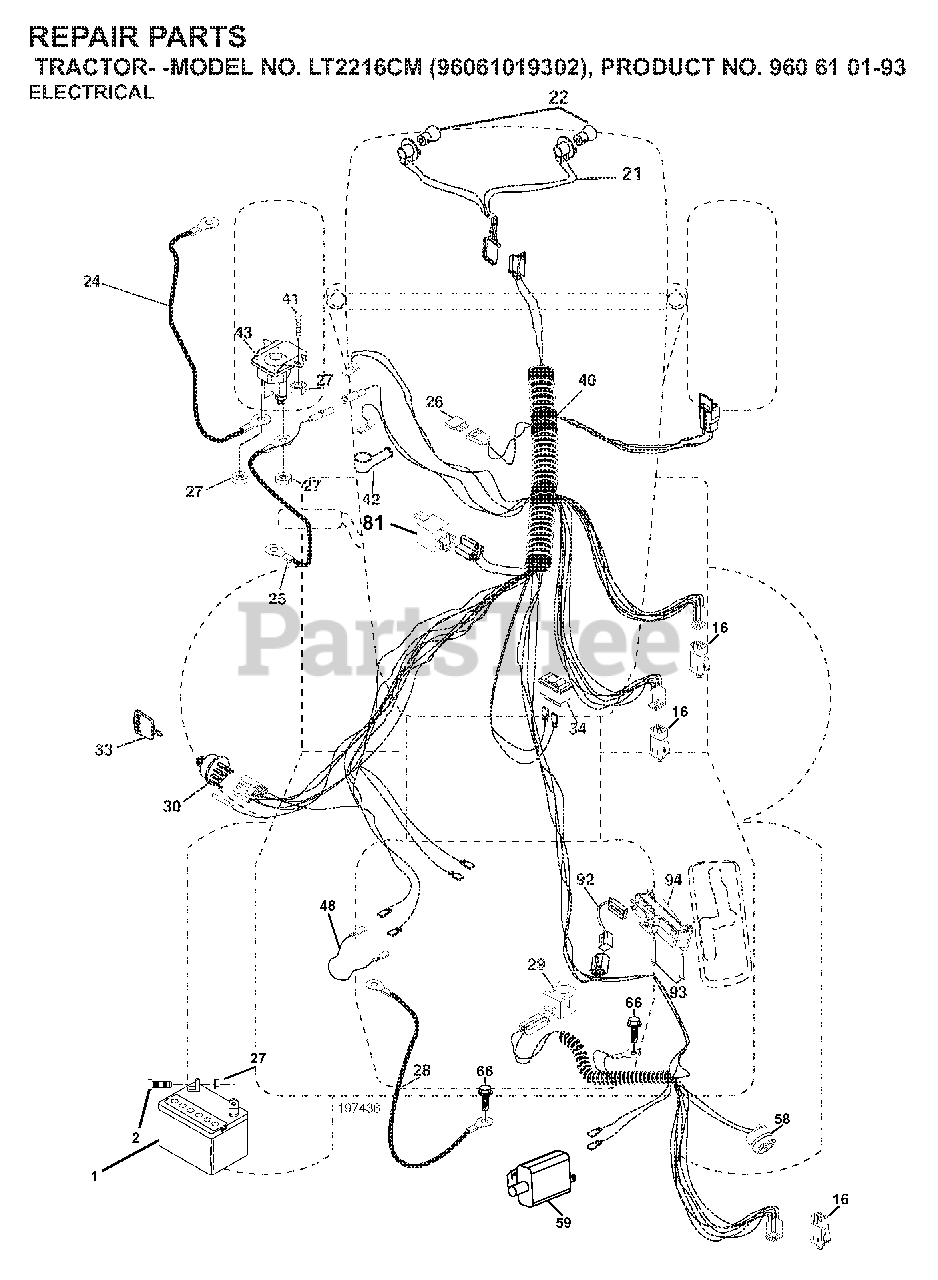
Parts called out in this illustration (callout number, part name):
1	BATTERY 12V .35 AMP
16	SWITCH INTERLOOK PUSH-IN
21	HARNESS ASSY LIGHT
22	LIGHTBULB
24	BATTERY CABLE GT
25	CABLE BATTERY
26	FUSE 20AMP
27	NUT
28	CABLE GROUND
29	SWITCH.SEAT.DP W/RAMPS
30	SWITCH.IGN.DELTA.W.LGH.ROS
33	KEY MLD GEN DELTA
34	SWITCH LT
42	TERMINAL COVER
43	SOLENOID.W/BRASS.PLUNG
58	BUZZER
81	RELAY.ASSY.T
92	HARNESS.PIGTAIL.CONSLE
93	SCREW.PLASTITE
94	MODULE.REVERSE.ROS
